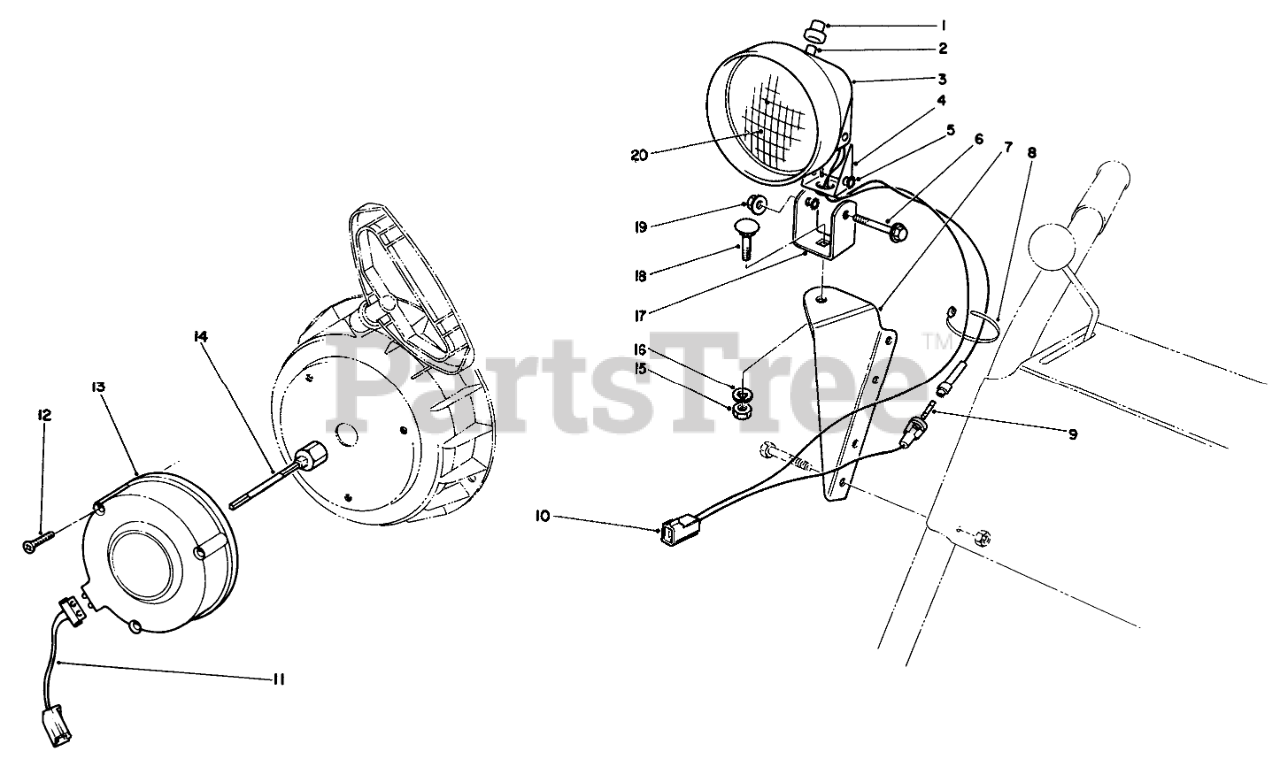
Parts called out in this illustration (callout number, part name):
1	Boot-Switch
2	SWITCH ASM
3	Bucket-Headlamp
4	Bracket
5	WASHER-LOCK
6	SCREW-HH
7	LAMP MOUNT B
8	TIE-CABLE
9	Fuse-7-1/2 Amp
10	WIRE ASM
11	Connector-Wire
12	SELF TAP SCREW
12	Alternator
14	Shaft-Alternator, 3 Inch
15	NUT-HEX
16	WASHER-LOCK/SP
17	BRACKET
18	BOLT-CARR
19	NUT-HF
20	BEAM-SEALED
